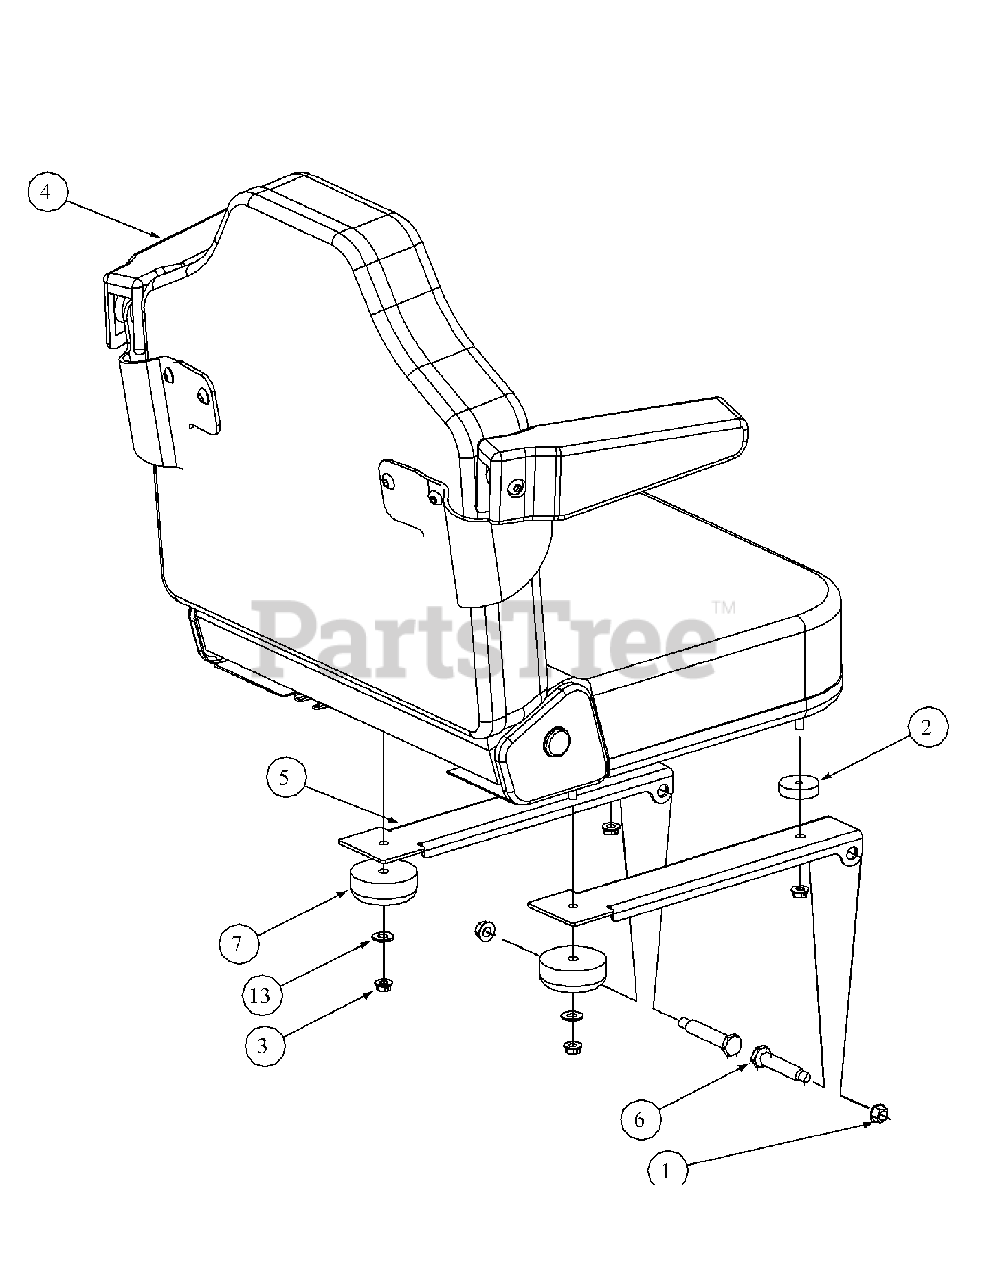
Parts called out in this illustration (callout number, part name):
1	Nut, Hex 3/8-16 Flange Lock
2	Spacer, 0.345 ID x 1.50 OD x .41
3	Lock Nut, Hex Flange, 5/16-18
4	Adjustable Seat, Black embossed,
5	Mounting Bracket, Seat
6	Shoulder Screw, .50x2.345, 3/8-16
7	Grommet, 2.5 OD x 1.0 Long
13	Washer
